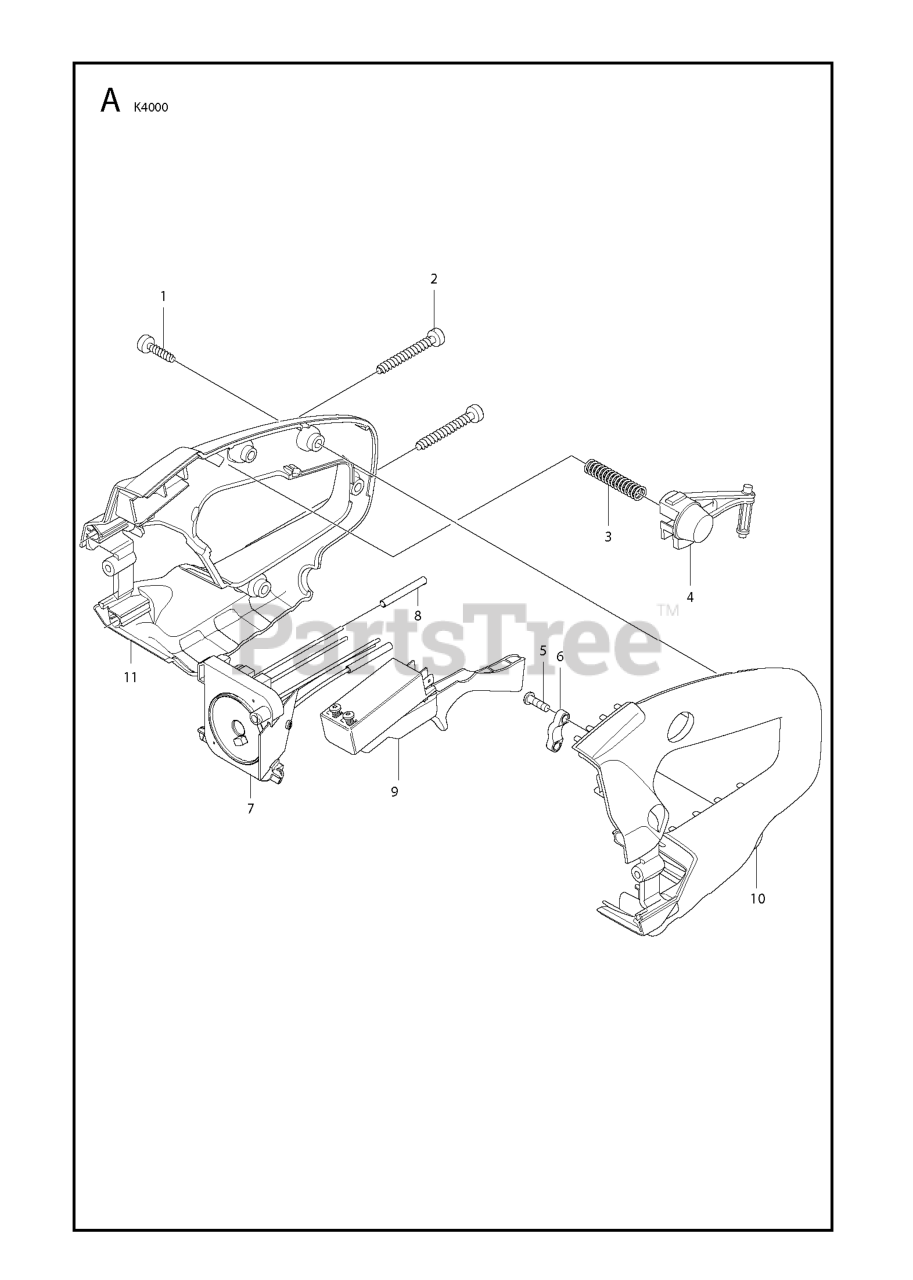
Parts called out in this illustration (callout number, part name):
4	LOCKING BUTTON K3000
7	HOLDER ASSY ELECTRONICS ASSY 2
8	SLEEVE RED: 0,5 - 1,5 MM2 HEAT
8	SLEEVE YELLOW: 3-6 MM2 HEAT SH
